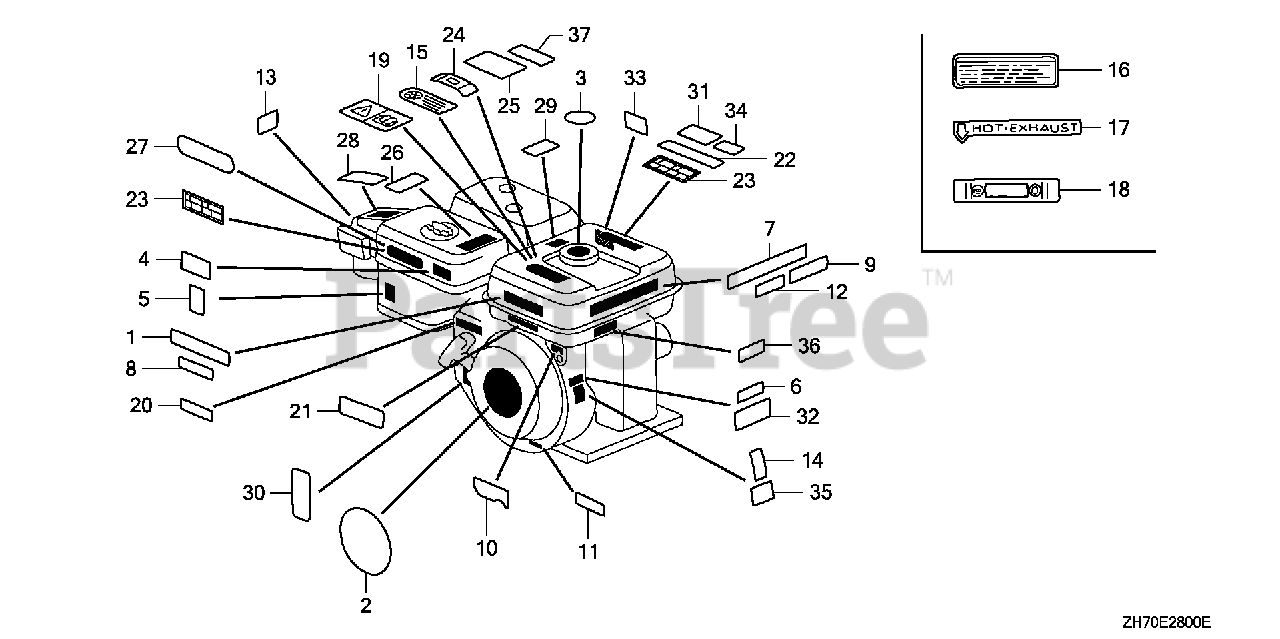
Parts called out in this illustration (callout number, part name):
1	LABEL, CAUTION (ENGLISH, ETC.)
2	EMBLEM
2	EMBLEM (4.0)
2	EMBLEM (GX120)
3	MARK, CAUTION
5	MARK, CHOKE
9	MARK, OIL ALERT (GERMAN)
9	MARK, OIL ALERT (FRENCH)
12	MARK, OIL ALERT (ENGLISH)
14	LABEL, SPECIFICATION (EXTERNAL)
29	LABEL, FUEL CAUTION
